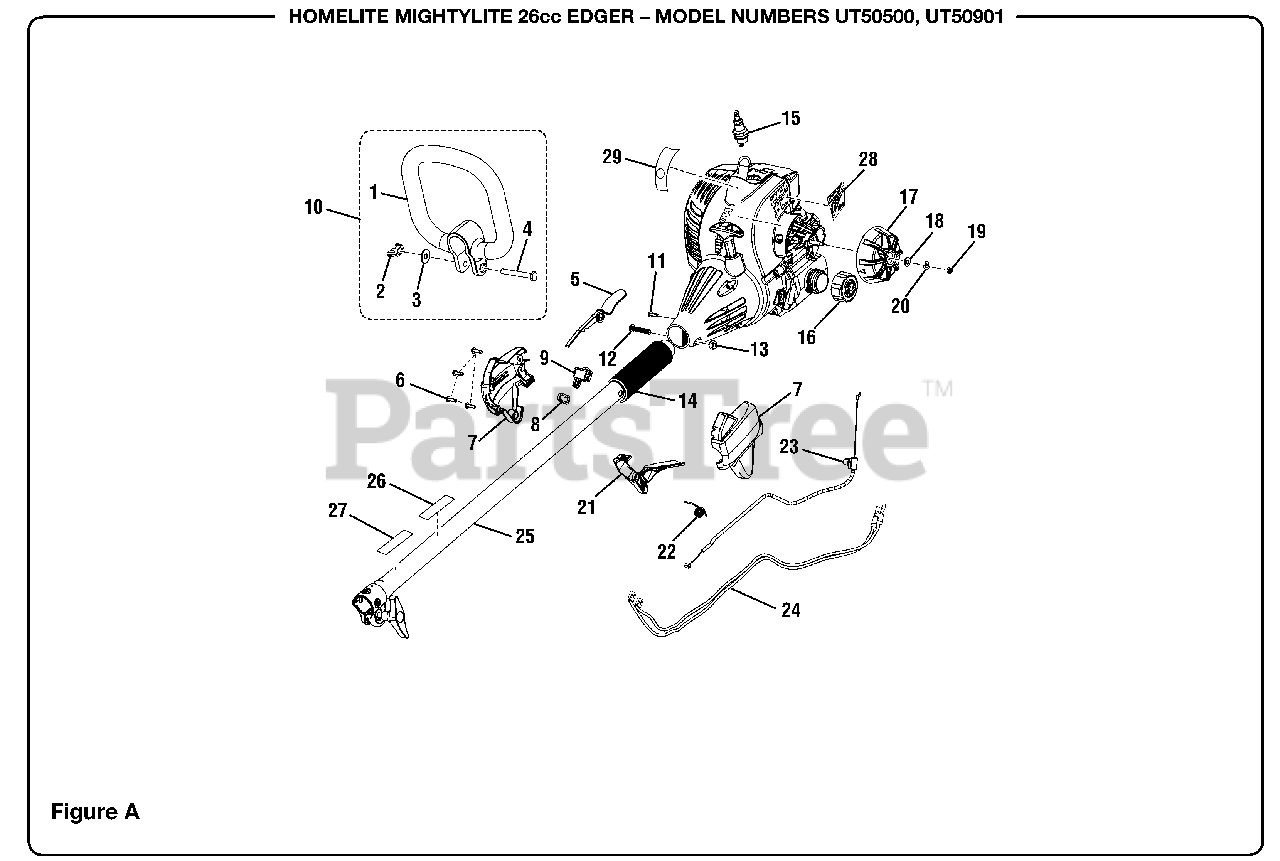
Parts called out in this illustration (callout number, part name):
2	Wing Nut (1/4-20)
4	Bolt (1/4-20 x 40 mm)
5	Throttle Lock
6	Screw (M4 x 20 mm)
7	Housing Assembly
8	Shoulder Strap Hook
9	Switch
10	Front Handle Assembly
11	Screw (8-16 x 5/16 in.)
12	Bolt (M6 x 20 mm)
13	Hex Nut (M6)
14	Rear Handle
15	Spark Plug
17	Choke Dial Cover
19	Hex Nut (M4)
20	Wavy Washer
21	Throttle Trigger
22	Torsion Spring
23	Throttle Cable
25	Upper Boom Assembly
26	Starting Label
27	Warning Label
28	Logo Label
29	Choke Label
